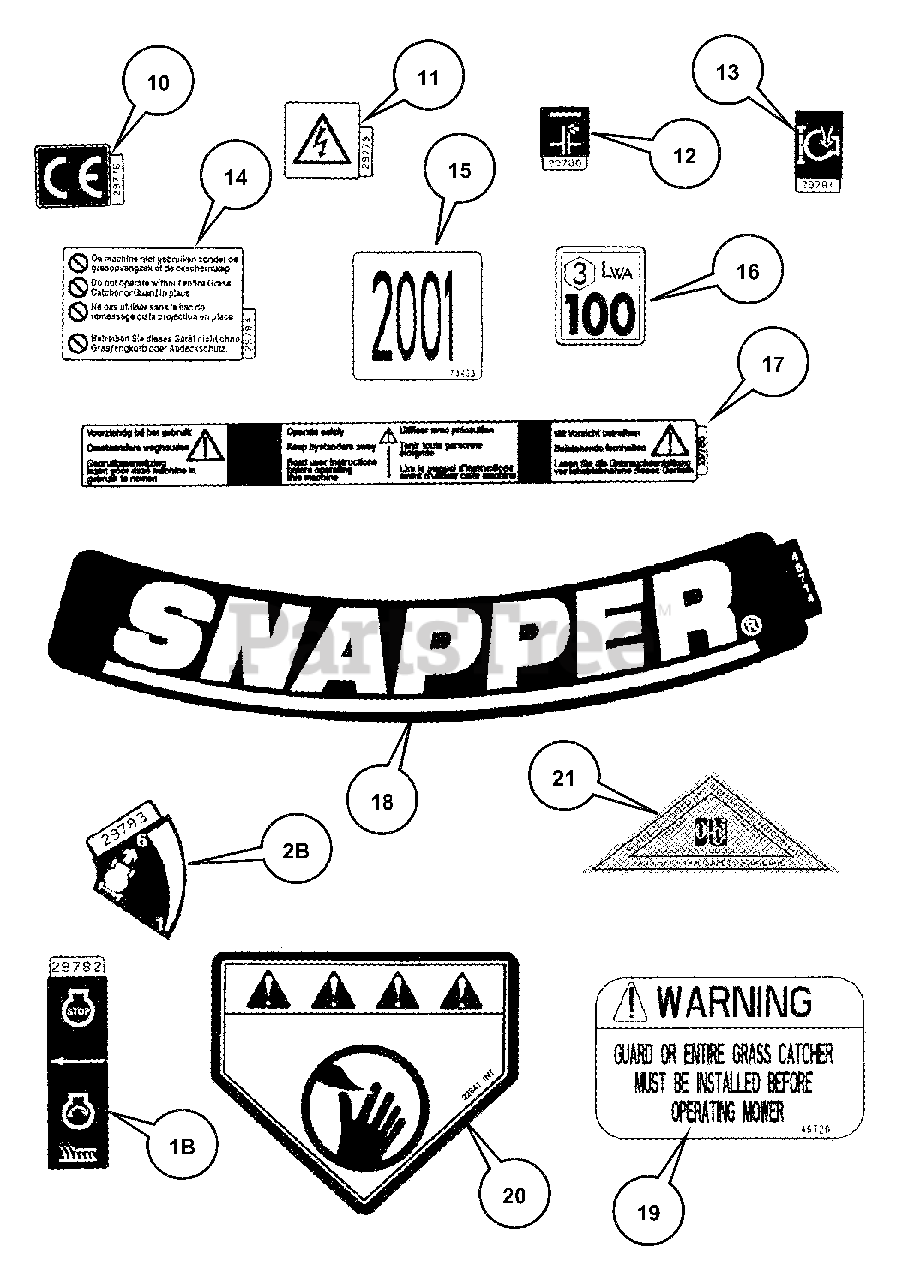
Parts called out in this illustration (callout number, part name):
1B	DECAL, Blade Control (Euro)
2B	DECAL, Speed Sector (Self-Propelled) (European)
10	DECAL, CE (European)
11	DECAL, Spark Plug (European)
12	DECAL, Primer (European)
13	DECAL, Air Filter (European)
14	DECAL, Deck/Chute (European)
15	DECAL, 2001 Year of Manufacture
16	DECAL, Noise (European)
17	DECAL, Operator Safety (European)
18	DECAL, Deck Snapper
19	DECAL, Chute/Deflector Warning
20	DECAL, Warning
21	DECAL, OPEI
